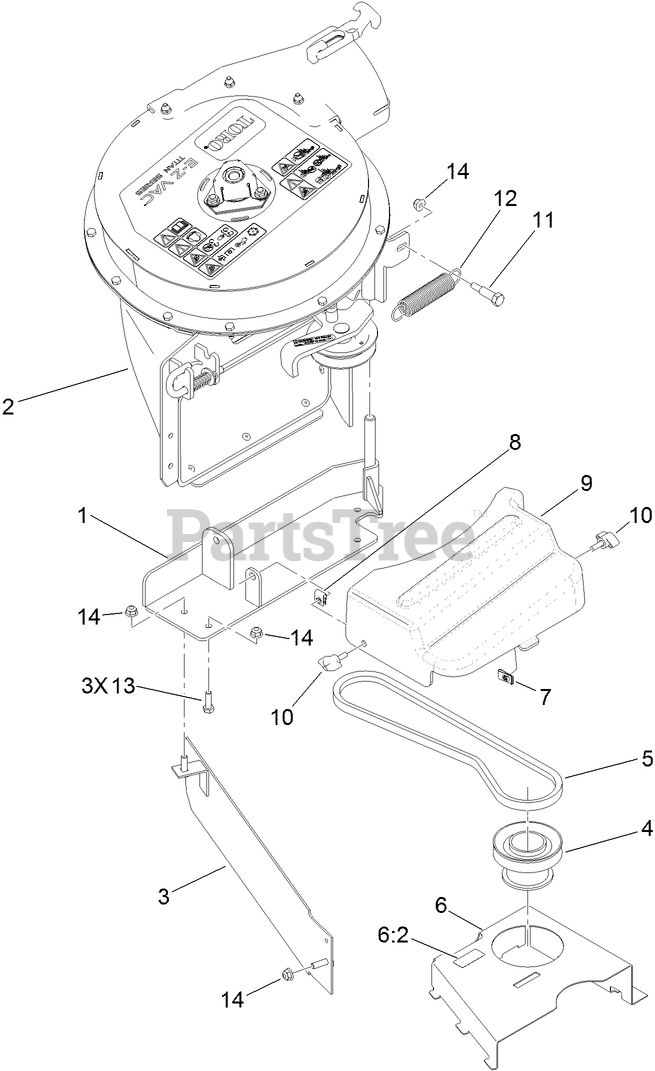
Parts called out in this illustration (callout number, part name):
1	SUPPORT-BLOWER
2	BLOWER HOUSING ASM
4	PULLEY-BAGGER
5	BELT-V
6	COVER ASM
6:2	DECAL-DANGER
7	NUT-SPEED
8	NUT-SPEED
9	COVER-BELT
11	SCREW-SHOULDER, HH
12	SPRING-EXTENSION
13	SCREW-HH
14	NUT-HF, NI
